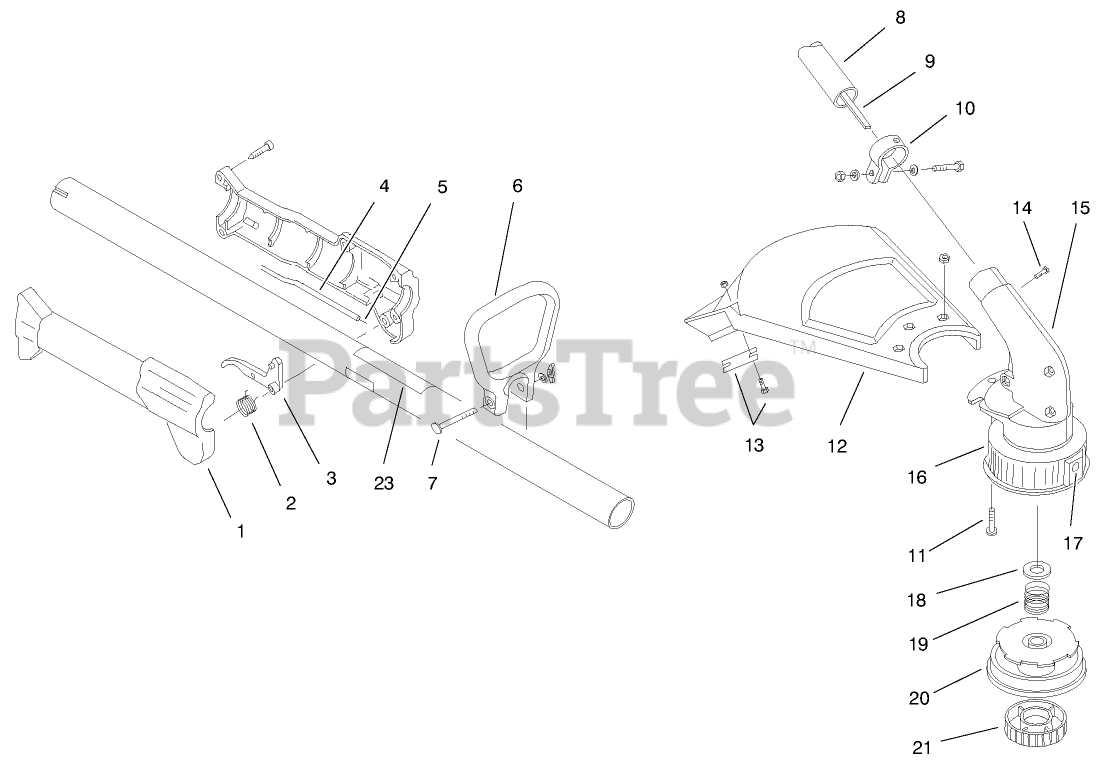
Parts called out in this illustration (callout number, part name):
1	Throttle Housing & Trigger Asm.
2	SPRING - TRIGGER
3	HSG - THROTTLE TRIGGER
4	Throttle Cable Housing
5	Throttle Cable
6	D-Handle
7	HARDWARE - D-HANDLE
8	Drive Shaft Housing Asm.
9	SHAFT - FLEX, 48.94
10	CLAMP ASM - UPPER
11	ASM - GUARD MTG SCREW
12	Guard and Blade Asm.
13	BLADE ASM
14	Anti-Rotation Screw
15	Gearbox Asm.
16	OUTER SPOOL EYELET ASM
17	EYELET
18	RETAINER WASHER(SET OF 10)
19	SPRING
20	REEL - INNER
21	SMALL BUMP KNOB ASM
23	DECAL - SAFETY SYMBOLS
